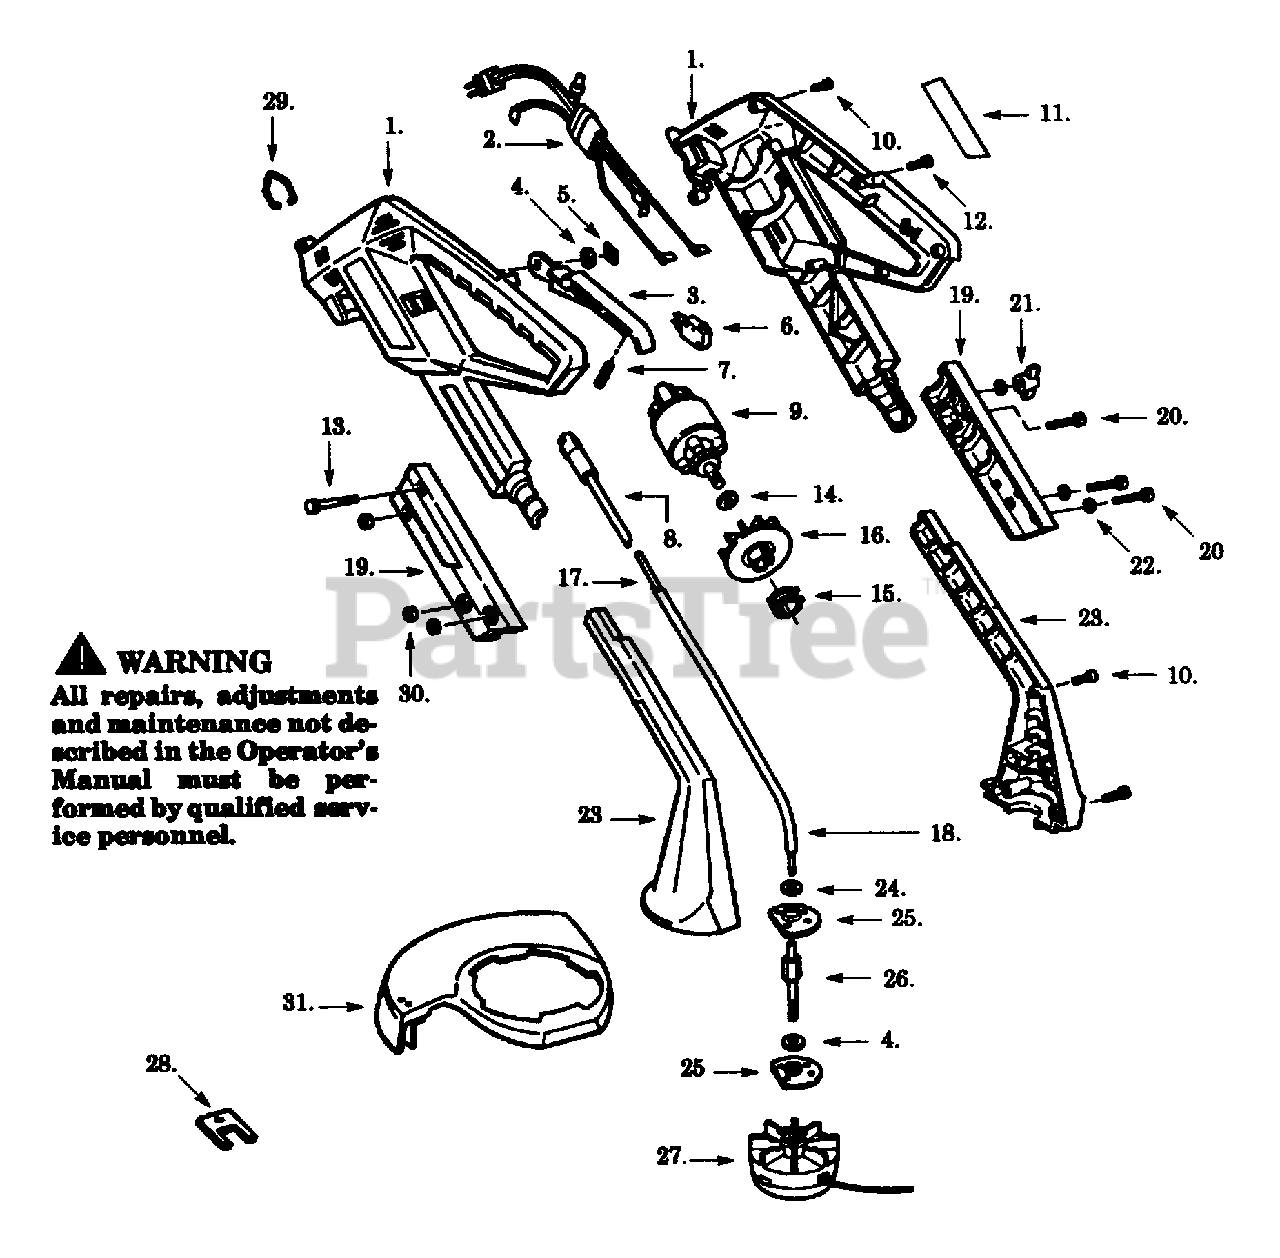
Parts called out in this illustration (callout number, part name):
1	Model PT1000-00,PT1200-00,PT1000-01A
1	Model PT1000-01,PT1200-01
2	Harness Ass'y.
4	Washer, (As required)
5	Push Nut
7	Trigger Spring
8	Upper Sleeve Model PT1000-01,PT1200-01, PT1000-01A
9	Motor Ass'y.
11	Warning Label (Not a serviceable part)
15	Fan Clamp Model PT1000-00,PT1200-00 Only
17	Model PT1000-00,PT1200-00
17	Model PT1000-01,PT1200-01,PT1000-01A
18	Model PT1000-00,PT1200-00
18	Model PT1000-01,PT1200-01,PT1000-01A
19	Housing Set
23	Spindle Housing Set
24	Felt Washer
25	Bearing Holder
26	Shaft Adapter
27	Model PT1000-00,PT1200-00
27	Model PT1000-01,PT1200-01,PT1000-01A
28	Spanner Wrench
31	Model PT1000-00,PT1200-00
31	Model PT1000-01,PT1200-01
31	Model PT1000-01A
